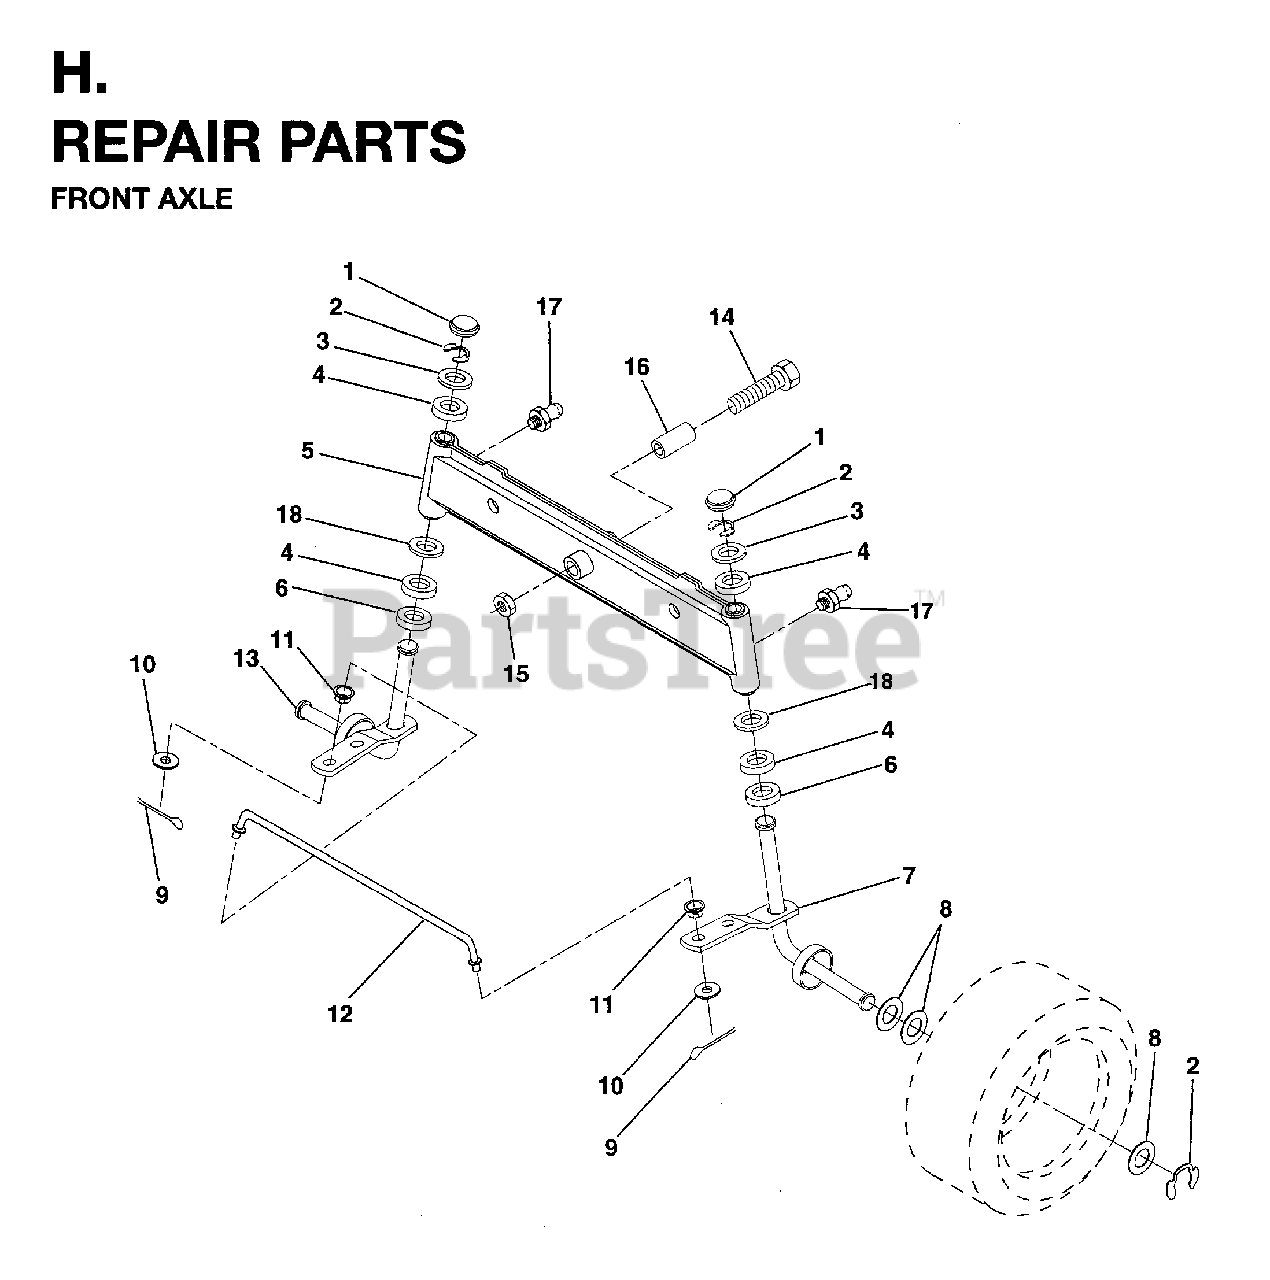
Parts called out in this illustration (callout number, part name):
1	CAP.SPINDLE
2	RING CLIP
4	BEARING.STEERING.COLUMN
5	AXLE ASSY
6	WASHER THRUST
7	SPINDLE ASSY RH NLA
9	COTTER PIN
10	WASHER
11	BUSHING.DRAGLINK
12	TIE ROD
13	SPINDLE ASSY LH
14	BOLT.HEX.5/8-11
15	LOCKNUT
16	BEARING
17	ZERK M
